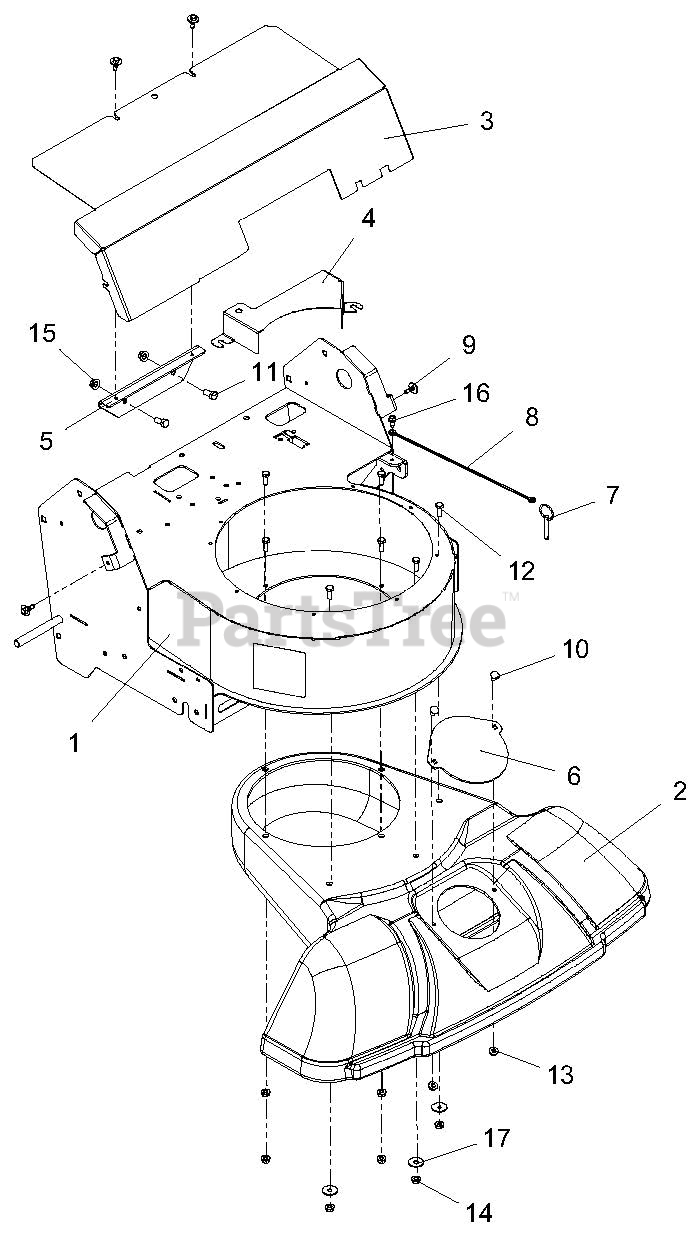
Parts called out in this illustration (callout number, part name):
1	WLDMT, FRAME - APV
2	INLET, UPPER
3	GUARD, TRANS - APV
4	GUARD, BELT - APV
5	BRKT, SUPPORT - TRANS GUARD
6	COVER, HOSE INLET-BLACK
7	PIN, RING DETENT .25 x 1.25
9	SCR, TAP .25-20 x .5 CAPTIVE
10	BLT-RDHDSQSHNK .25-20 x .50 YWZC
11	BLT-HEX .31-18 x .75 GR5 YWZC
12	BLT-HEX .25-20 x .75 GR5 YWZC
13	NUT, LK-CTR-FLG .25-20 YWZC
14	NUT, LK-TOP-FLG .25-20 YWZC
15	NUT, LK-TOP-FLG .312-18 YWZC
16	SCR-TAP .25-20 x .50 HWH TR YWZ
17	WSHR-FL-STL .281 x 1.000 x .063 YWZC
